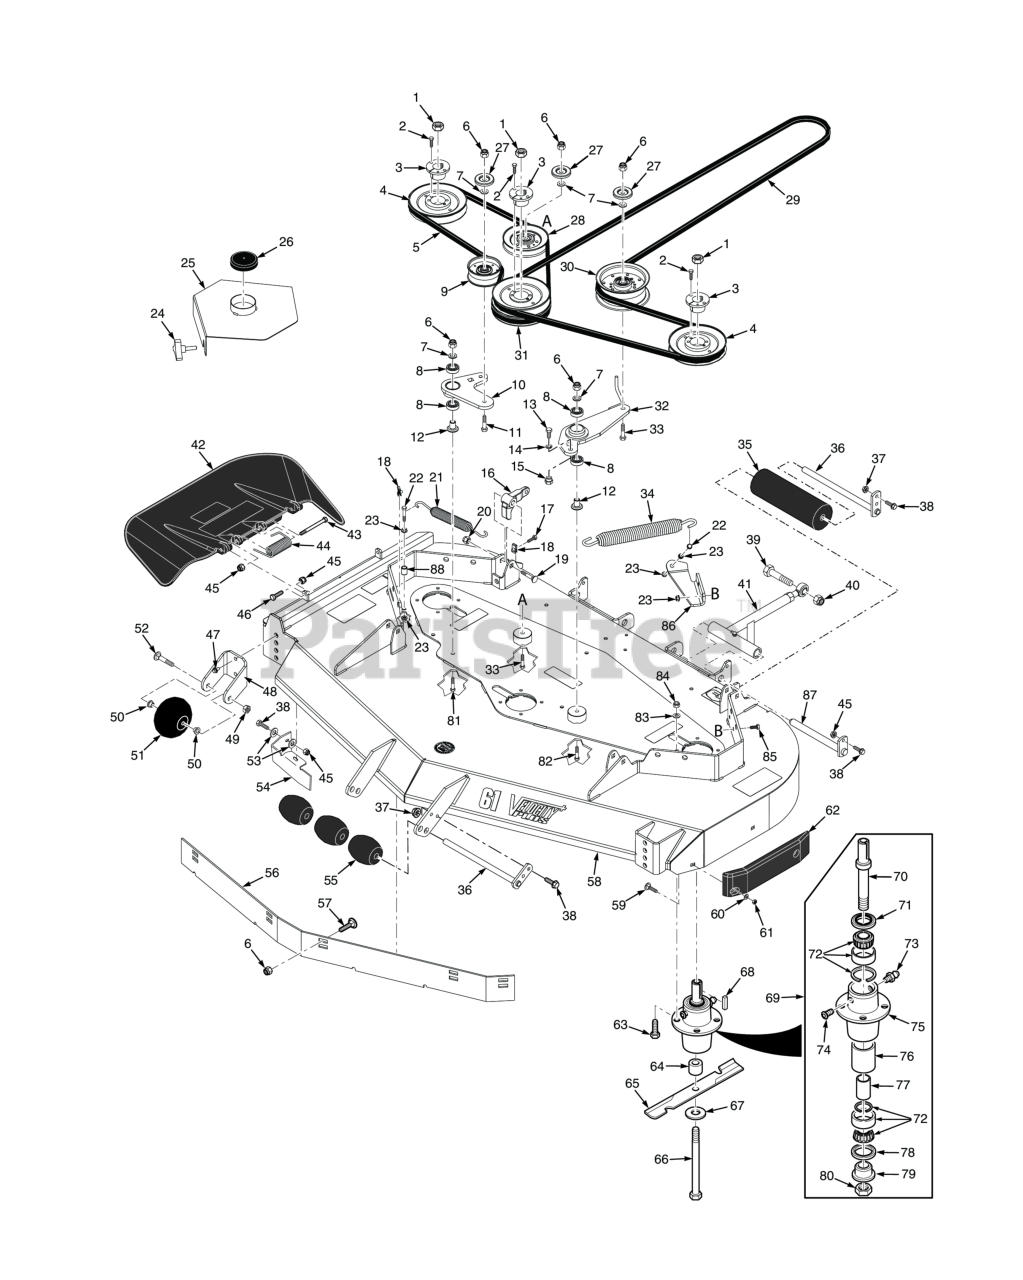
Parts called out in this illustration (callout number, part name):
1	Hex Locknut, Elastic Stop, 3/8-16
2	Bolt, Hex Head 1/4-20 x 1" Grade 8 Black
3	Hub, Tapered 1-1/8" Bore
4	Pulley, Tapered Bore 6.33" Dia.
5	Belt, Deck Drive R.H.
6	HEX NUT, ELASTIC STOP LOCK, 3/8-16
7	Flatwasher, 3/8 (.391 x .938 x .105 HD) Grade 8
8	BEARINGS, BALL, NEUTRAL RETURN
9	Pulley, 3-1/2" Dia.
10	Idler Arm
11	Capscrew, Hex Head 3/8-16 x 2-1/2"
12	Pivot, Idler Short
13	Bolt, Hex Head 7/16-14 x 1"
14	Lockwasher, 7/16� Spring
15	Boss, Spring Anchor - LH
16	Lever, Deck Level
17	Bolt, Hex Head 3/8-16 x 2" Special Lock
18	U-Nut, 3/8-16 (short)
19	Bolt, Carriage 7/16-14 x 2-1/4"
20	HEX LOCKNUT, ELASTIC STOP, 7/16-14
21	Spring, RH Deck Drive
22	Bolt, Hex Head 3/8-16 x 1-1/2" Grade 8 Black
23	NUT, 3/8-16 SERRATED FLANGE HEX HEAD
24	Knob, w/stud 3/8-16 x 1-1/4"
25	Belt Cover Weldment (incl. #26)
27	Quick Pin, 5/16" Dia.
28	IDLER PULLEY, "V" GROOVE
29	BELT, DECK DRIVE - SMTC-61V
30	Pulley, Idler 5" Dia.
31	Pulley, Double Groove 6.33" Dia.
32	Idler Arm
33	Bolt, Hex Head 3/8-16 x 3" - 52"
34	Spring, L.H. Deck Drive
35	Wheel, Anti-ScalpRelief Fitting, Tapered Spindle
36	Shaft Weldment, Guide Roller
37	Nut, Flange Head Elastic Stop 5/16-18
38	Bolt, Heax Head 5/16-18 x 1" (48V / 52V)
39	BOLT, HEX HEAD 5/8-11 X 4-1/2"
40	HEX LOCKNUT, ELASTIC STOP, 5/8-11
41	Push Arm (Includes 64,60,62)
42	Discharge Chute Advantage - Large
43	Bolt, 5/16-18 x 4-3/4" Hex Head
44	Spring, Discharge Chute
45	HEX NUT, ELASTIC STOP LOCK, 5/16-18
46	Bolt, Hex Head 5/16-18 x 1-1/2" - Front
47	Capscrew, 3/8-16 x 1.0" Serrated Flange Hex Hd
48	Bracket, Anti-Scalp Wheel
49	Bolt, Hex Head 3/8-16 x 1" Ser. Flg.
50	Bushing, .376" I.D. Oilite
51	Bolt, Carriage 3/8-16 x 4"
52	Bolt, Hex Head 3/8-16 x 3-1/2"
53	Flatwasher, 5/16-.375 x .875 x .083 (35BV & 37BV-EFI)
54	Turbo Baffle, Bolt On
55	Wheel, Anti-Scalp
56	Baffle Custom-Cut, 61V (7-Position)
57	Carriage Bolt, 3/8-16 x 1.0"
58	Cutter Deck Velocity Plus
59	Bolt, 5/16-18 x .75 RHSN Carriage
60	Flatwasher, 5/16-.344 x .688 x .065 (48V / 52V)
61	Nut, Center Lock, 5/16-18(32)
62	Pad, Deck Wear
63	Bolt, Hex Head 5/16-18 x 1-3/4" Grade 8
64	Spacer, Spindle Bottom
65	Cutter Blade, 21" Standard
66	BOLT, HEX HEAD, 5/8-11 X 9-1/2 GR.5
67	Flatwasher, 5/8-.688 x 1-3/4 x .134 HD
68	Key, 1/4 x 1/4 x 2.0"
69	Cutter Spindle Assembly
70	Spindle Shaft, Tapered Brng
71	SEAL, 2.00 O.D. X 1.50 BORE
72	Tapered Bearing Set (Two Bearings W/Race)
73	GREASE FITTING, STR. 1/4-28 SELF TAP.
74	RELIEF FITTING, TAPERED BEARING SPINDLE
75	Housing, Spindle
76	Spacer, Outside, Cutter Spindle
77	SLEEVE, CUTTER SPINDLE
78	Seal, 2.00" O.D. x 1.625" Bore
79	SPINDLE BUSHING, BOTTOM
80	Nut , Spec ial 1 -1/ 1 6 - 1 8
81	Bolt, Hex Head 3/8-16 x 2-1/4" - 61"
82	Capscrew, Hex Head 3/8-16 x 3.25"
83	Lockwasher, 5/16 (.317 x .586 x .078) Helical Spring
84	Lock Nut, 5/16-18 Elastic Stop Grade 8
85	Bolt, Hex Head, 3/8-16 x 1 Gr. 5
86	Bracket, Spring Anchor
87	Shaft Weldment, Pusharm
88	SPACER, IDLER
